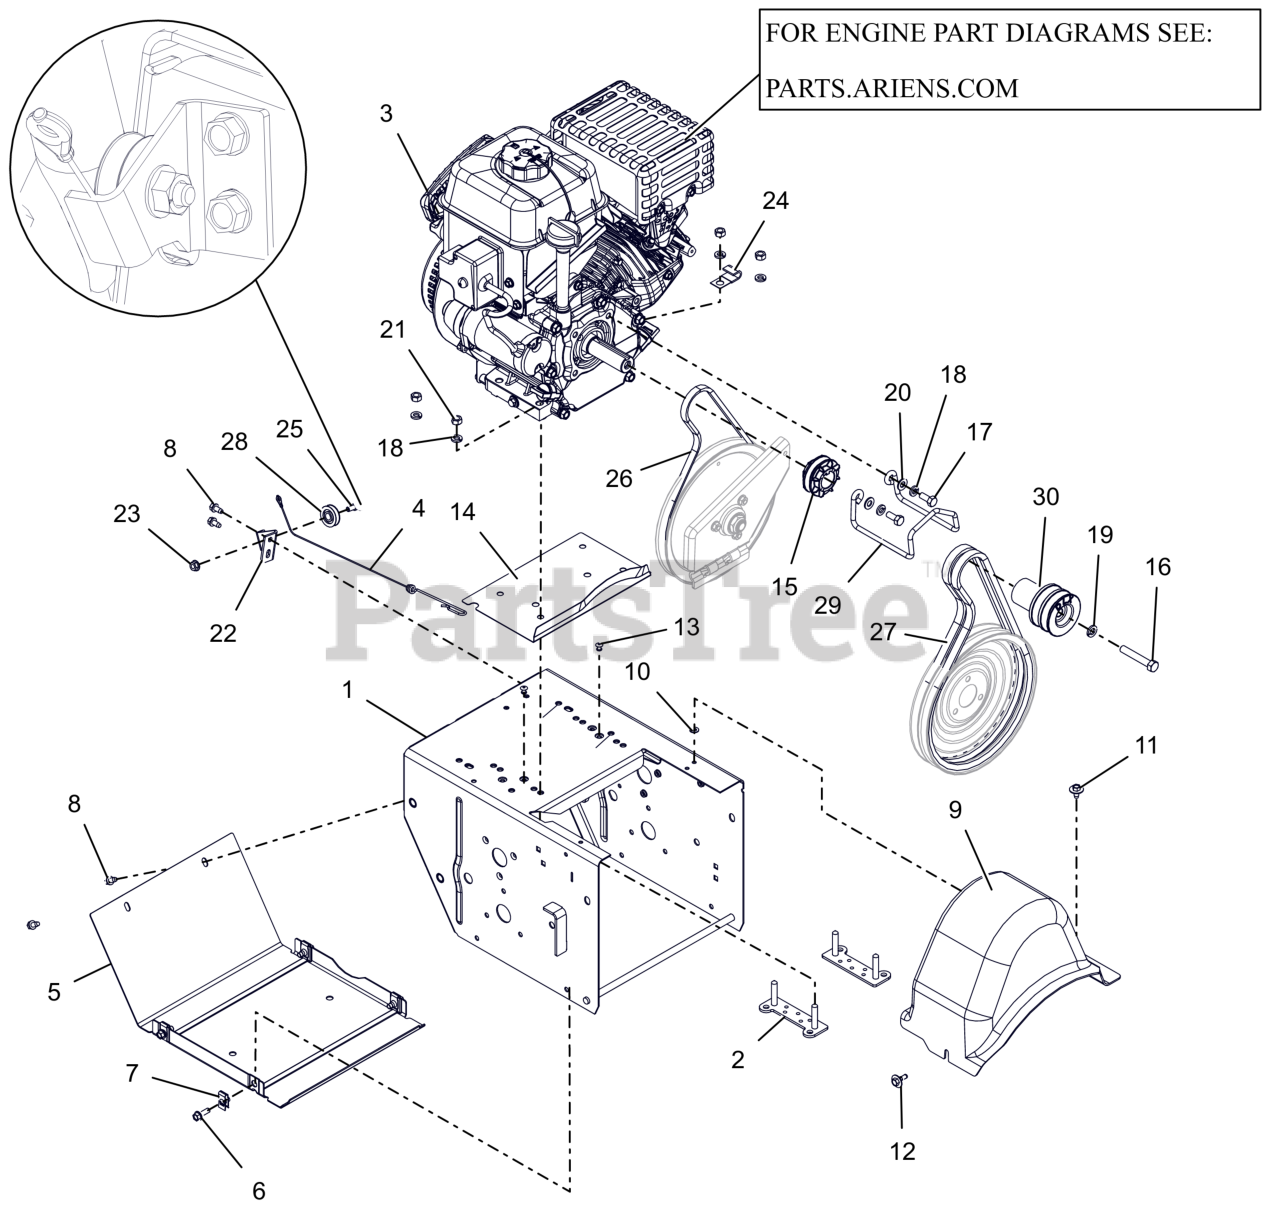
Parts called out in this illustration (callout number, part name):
1	FRAME, MAIN - 14GA DELUXE (ORANGE)
2	STRAP, BOLT - SMALL ENGINE
3	ENGINE, ARIENS AX254 240V/60W
4	CABLE, LOWER TRACTION,SS & PRO
5	COVER, BOTTOM
6	BLT, HWH .25-20X.75 G5 ZCC
7	NUT-RTNR .25-20X.56
8	SCR-TAP .25-20X.50 HWH ZCC
9	COVER, BELT-SMALL
10	NUT-PUSH .25X.50 O.D.
11	SCR, TAP .25-20X.50 LG HWH ZCC
12	SCR-TAP .25-20X.5 CAPTIVE
13	RVT, POP .1875 ZCC
14	BAFFLE, WATER-SMALL
15	SHEAVE, DRIVE
16	BLT, HEX .38-24X2.25 G5 ZCC
17	BLT, HEX .31-24X.750 G5 ZCC
18	WSHR, LK-HVY .312X.097 ZCC
19	WSHR,LK-REG .375X.094 ZCC
20	WSHR,FLT .344X.688X.065 ZCC
21	NUT, HEX .312-18 ZCC
22	BRACKET, CABLE PULLEY
23	NUT-LK-TOP-FLG .250-20 GF ZCC
24	J-CLAMP
25	BOLT, SHLDR -.375 X .375 X .25-20
26	V-BELT, 3L-WRAPPED
27	V-BELT, HA-RAW EDGE (SET)
28	PULLEY, CABLE
29	FINGER, BELT
30	SHEAVE, ATTACHMENT - STANDARD 2 GRV
